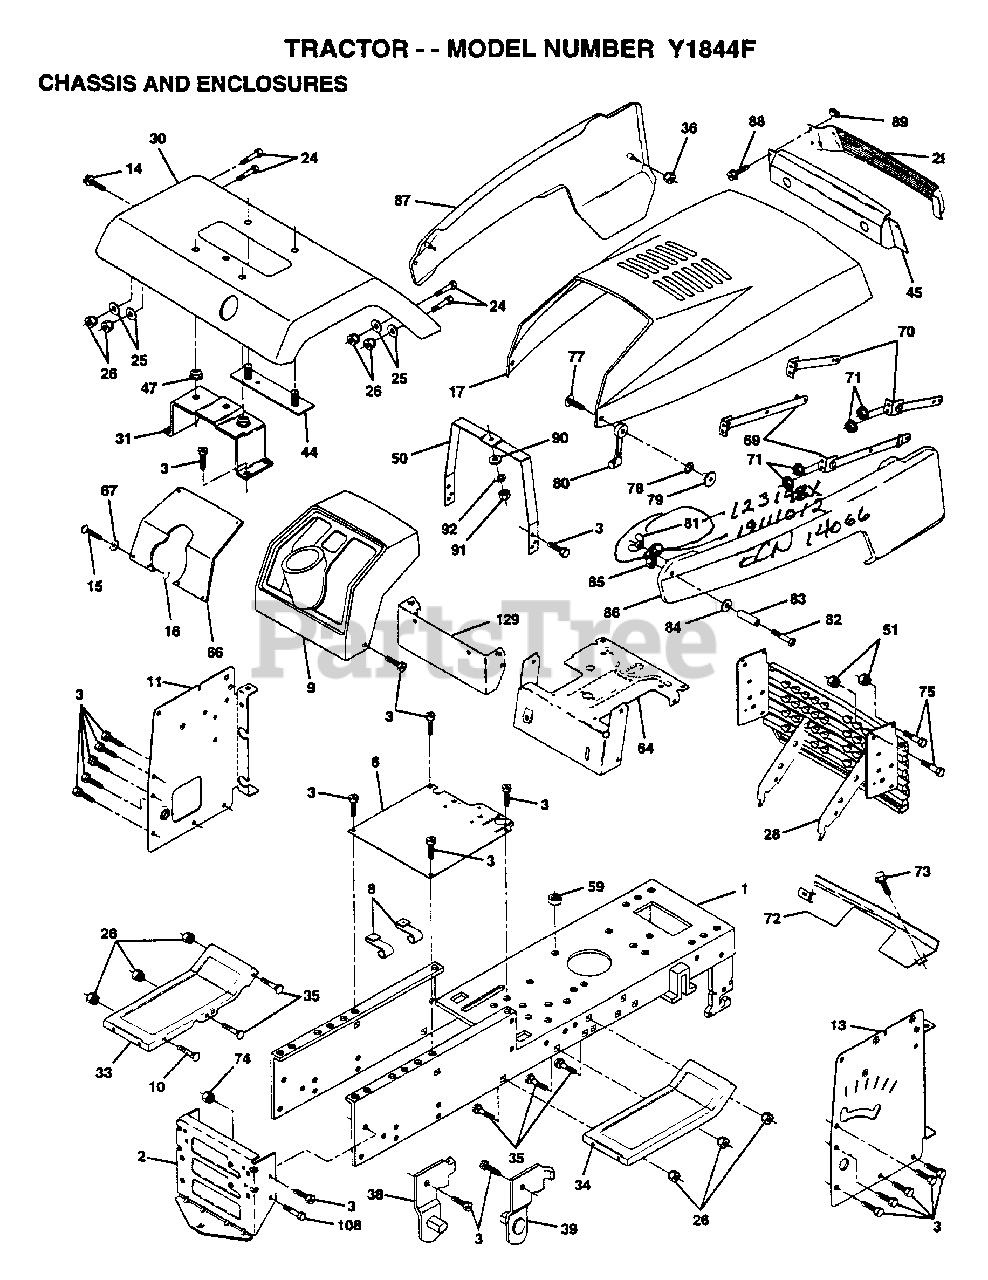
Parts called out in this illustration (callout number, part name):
1	CHASSIS.WLD.11GA
2	DRAW BAR
3	SCREW
8	"CLIP,INSULATOR"
9	DASHBOARD BLACK
11	PANEL.DASH.LH.PNT
13	PANEL.DASH.RH.PNT
14	SCREW
15	SCREW
24	BOLT
25	WASHER
26	NUT
29	LENS LT
30	FENDER.PNT.
31	BRKT.ASM.FENDER
35	BOLT
36	PAL NUT LT
38	BRACKET ASM LH
39	BRACKET ASM RH
44	STRAP ASM FENDER
47	NUT-PUSH YT
50	DASH.SUPT.YP/HUSQ
66	PLATE SLKSCR YP
67	WASHER
71	NUT HXKEP 1/4X20
72	STRAP.GRILLE.PNT.
73	SCREW CRT
74	NUT
77	SCREW
78	WASHER LOCK #10
79	WELDNUT
80	HOOD LATCH T
82	SCREW
83	SPACER LT
84	WASHER
86	PANEL SIDE RH
89	"""J"" FASTENER LT"
90	WASHER PM
92	LOCKWASHER
129	DASH.EXT.PNT.
